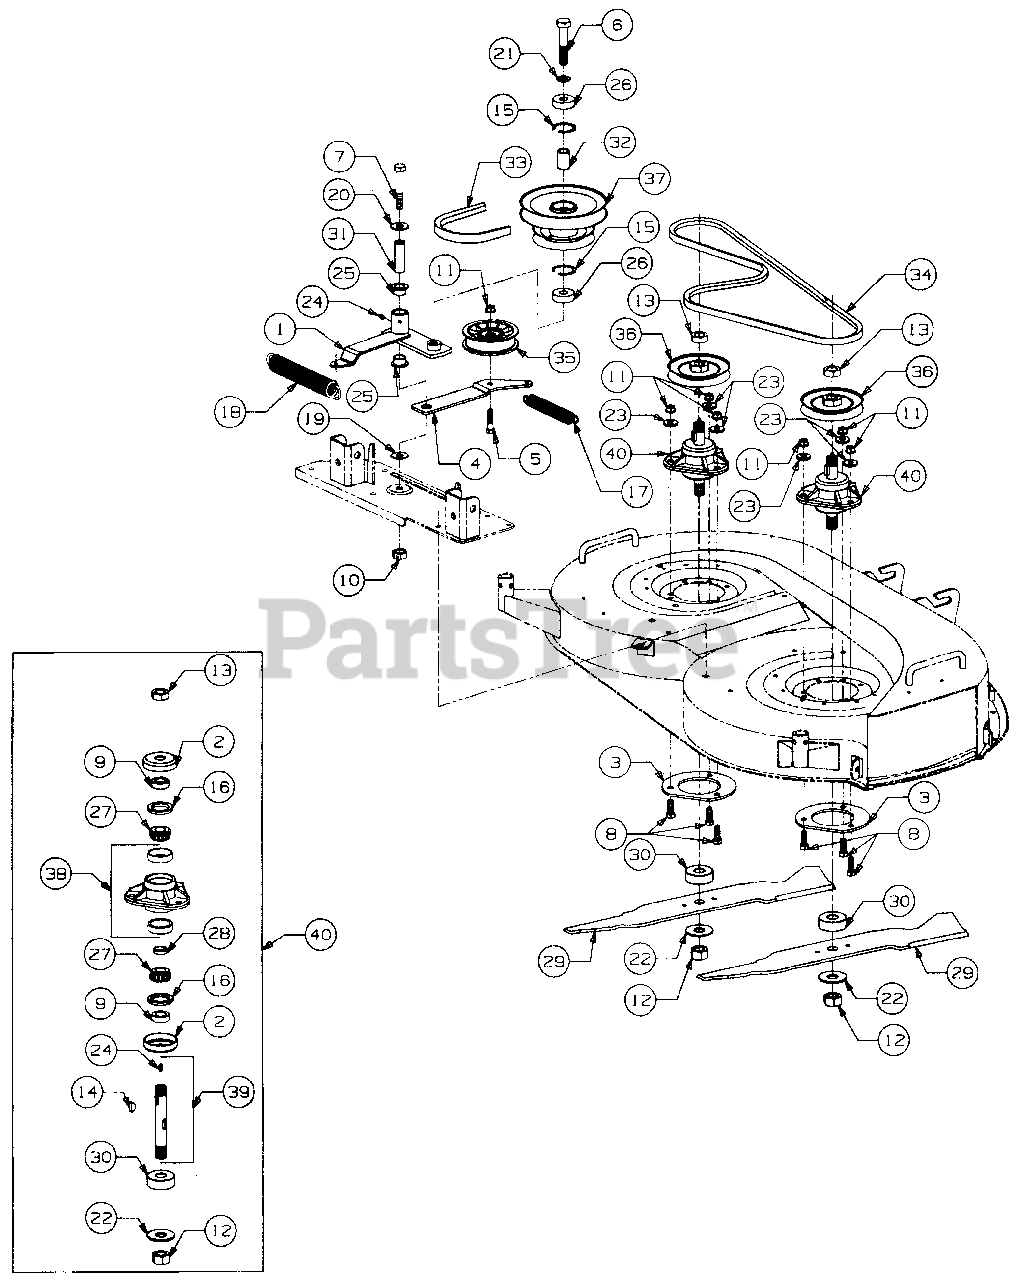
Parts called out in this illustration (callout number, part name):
2	Cup, Spindle Hdn
3	Plate, Spindle Mounting
5	Screw, Hex Cap 3/8-16 x 1.5 GR5
6	Screw, Hex Cap 5/8-18 x 3.0 GR5
7	Screw, Hex Cap 1/2-20 x 3.0 GR8
8	Screw, Hex Cap 3/8-16 x 1.25 GR5
9	Spacer, .755 x 1.25 x .44
10	Nut, Hex Center Lock, 1/2-20
11	Nut, Hex Flange Lock, 3/8-16
12	Nut, Hex, 3/4-16 GR8
13	Nut, Hex Jam, 3/4-16 GR5
14	Key, #91 Woodruff, 1/4 x 3/4 Hdn
15	Snap Ring, Internal
16	Seal, Oil, 1.25 x 1.874 x .25
17	Spring, Extension, .88 x 6.12
18	Spring, Extension, 1.25 x 8.15
19	Washer, Flat, .531 x 1.25 x .036
20	Washer, Flat, .531 x 1.25 x .100
21	Washer, Flat, .63 x 1.0 x .063 Hdn
22	Washer, Flat, .781 x 2.0 x .105
23	Washer, Flat, .385 x 1.0 x .135
24	Fitting, 3/16 Drive Lube
25	Bearing, Flange, 3/4 ID x .53 Lg
26	Bearing, Ball, .62 ID x 1.57 OD
27	Cone, Bearing
28	Spacer, Bearing
29	Blade, Low Lift, 21.20 Lg
30	Spacer
31	Spacer, Idler Brkt .50 ID x .75 OD x 2.25 Lg
32	Spacer, Pulley .635 ID x .88 OD x 1.25 Lg
33	Belt, PTO, B-Section x 112.4 Lg
34	Belt, Spindle, A-Section x 62 Lg
35	Pulley, Flat Idler, 3.5 OD
36	V-Pulley, 4.62 OD
37	Pulley, Double
38	Housing w/Cups, Spindle
39	Kit, Shaft w/Seal
40	Spindle Assembly, Blade
